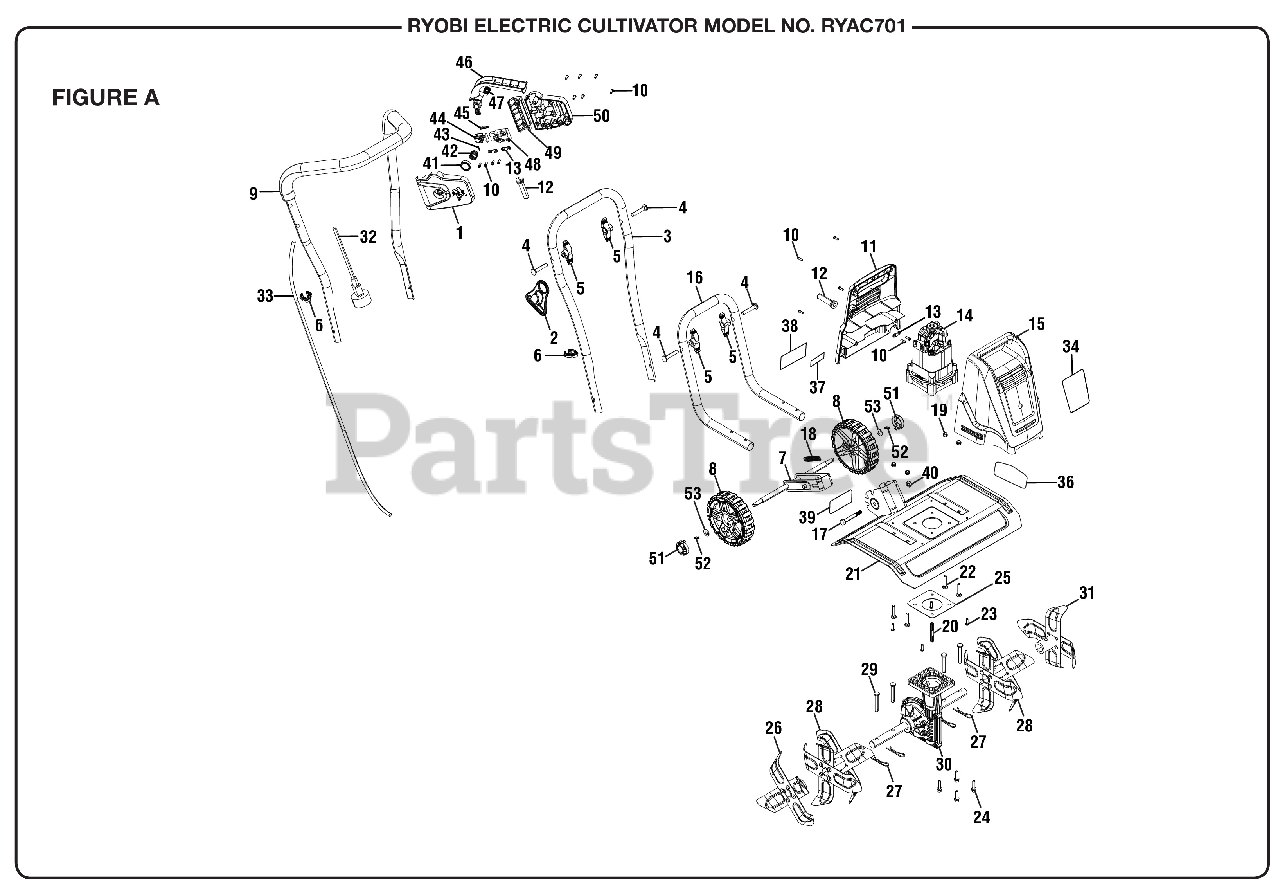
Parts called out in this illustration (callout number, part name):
1	Switch Box (Upper)
2	Cord Retainer
3	Lower Handle
4	Carriage Bolt (M8 x 45 mm)
6	Cord Hook
7	Wheel Height Adjusting Assembly
8	Wheel Assembly
9	Upper Handle Assembly
10	Screw (M4 x 12 mm, Pan Hd.)
11	Motor Housing (Rear)
12	Bend Relief
13	Cord Clamp
14	Motor Assembly
15	Motor Housing (Front)
16	Handle Frame (Lower)
17	Bolt (M6 x 50 mm, Hex Hd.)
18	Height Adjustment Spring
19	Lock Nut (M6)
21	Blade Shield
22	Carriage Bolt (M6 x 35 mm)
23	Screw (M5 x 16 mm, Pan Hd.)
24	Screw (M6 x 25 mm, Pan Hd.)
26	Blade Assembly (Right)
27	Cotter Pin
28	Blade Assembly
29	Clevis Pin
30	Transmission Assembly
31	Blade Assembly (Left)
32	Power Cord w/Plug
33	Power Cord
34	Logo Label
35	Icon Warning Label
36	Warning Label (French/Spanish)
37	No Hands/No Feet Label
38	Data Warning Label
39	Wheel Adjustment Label
40	Lock Nut (M8)
41	Switch Button
42	Compression Spring (Switch Button)
44	Switch Push Rod
45	Compression Spring (Switch Push Rod)
47	Torsion Spring (Trigger Lever)
49	Handle Fixing Plate
50	Switch Box (Lower)
51	Wheel Hub
52	Steel Hook
53	Washer (ID10 x OD18 x 1.5t)
